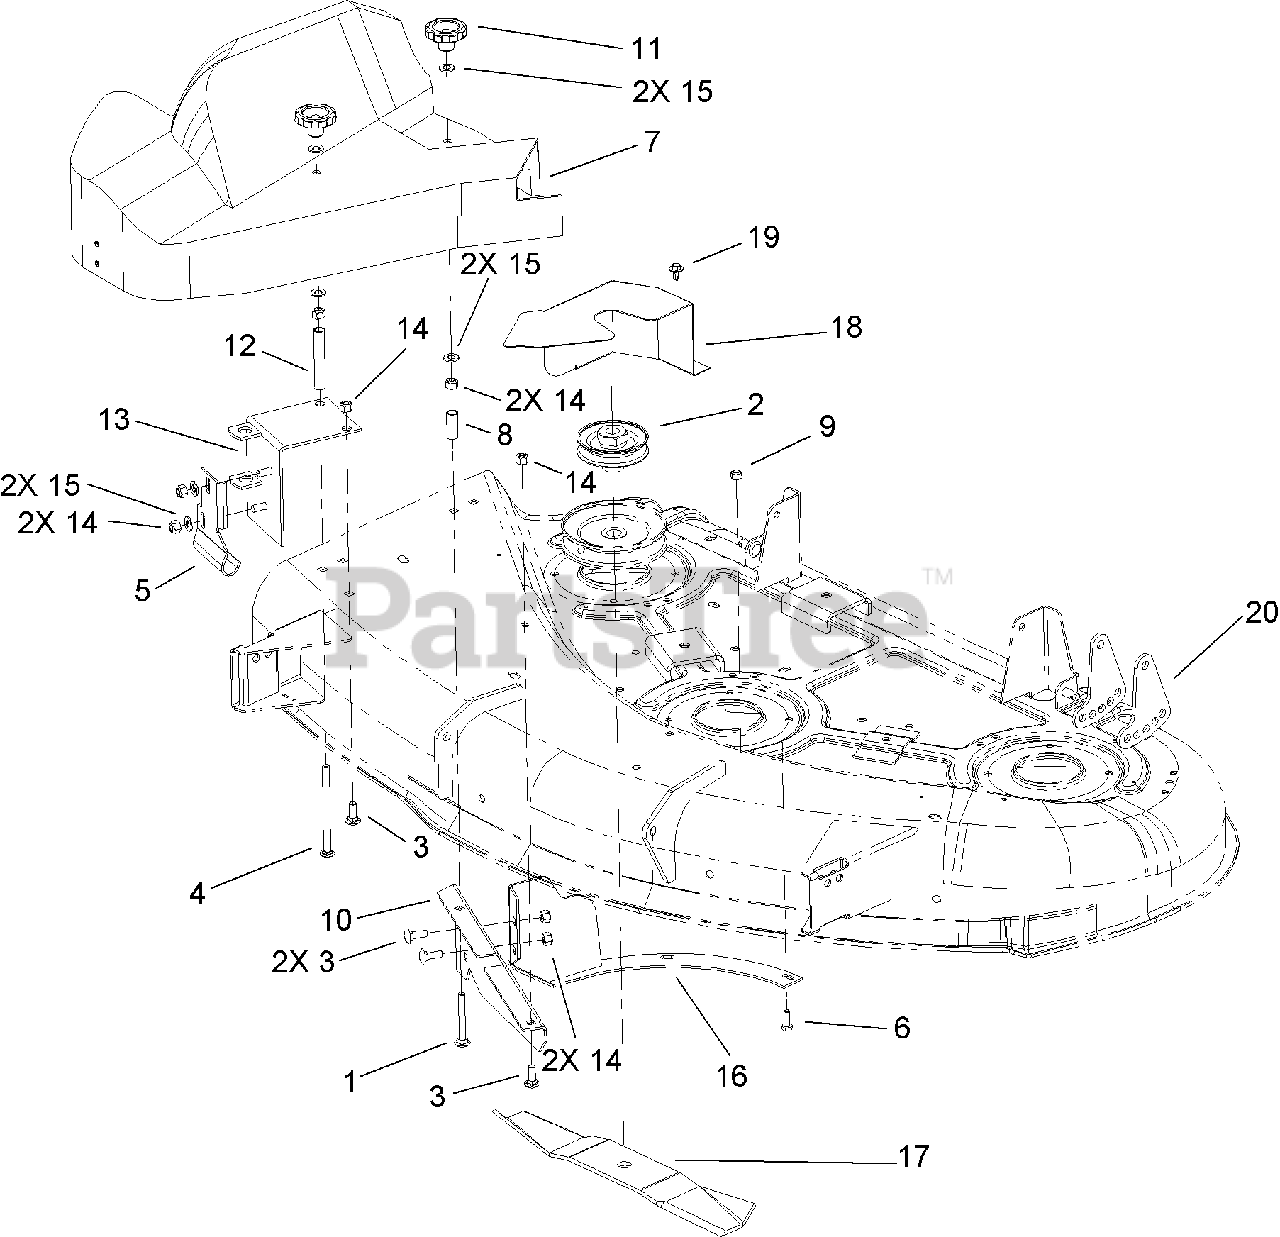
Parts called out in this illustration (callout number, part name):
1	SCREW-CARR
3	SCREW-CARR
4	SCREW-CARR
5	Bracket-Pivot
6	SCREW-HH
7	BELT SHIELD ASM
8	TUBE-LATCH
9	NUT-LOCK, NI
10	BAFFLE-REAR
12	TUBE-SPACER
13	Pivot-Bracket
14	NUT-LOCK, NI
15	WASHER-FLAT
16	RH BAGGING RING ASM
17	BLADE-LIFT, HIGH
18	COVER-PULLEY
19	SCREW-HHF
20	LINK-ADJUSTMENT, HOC
